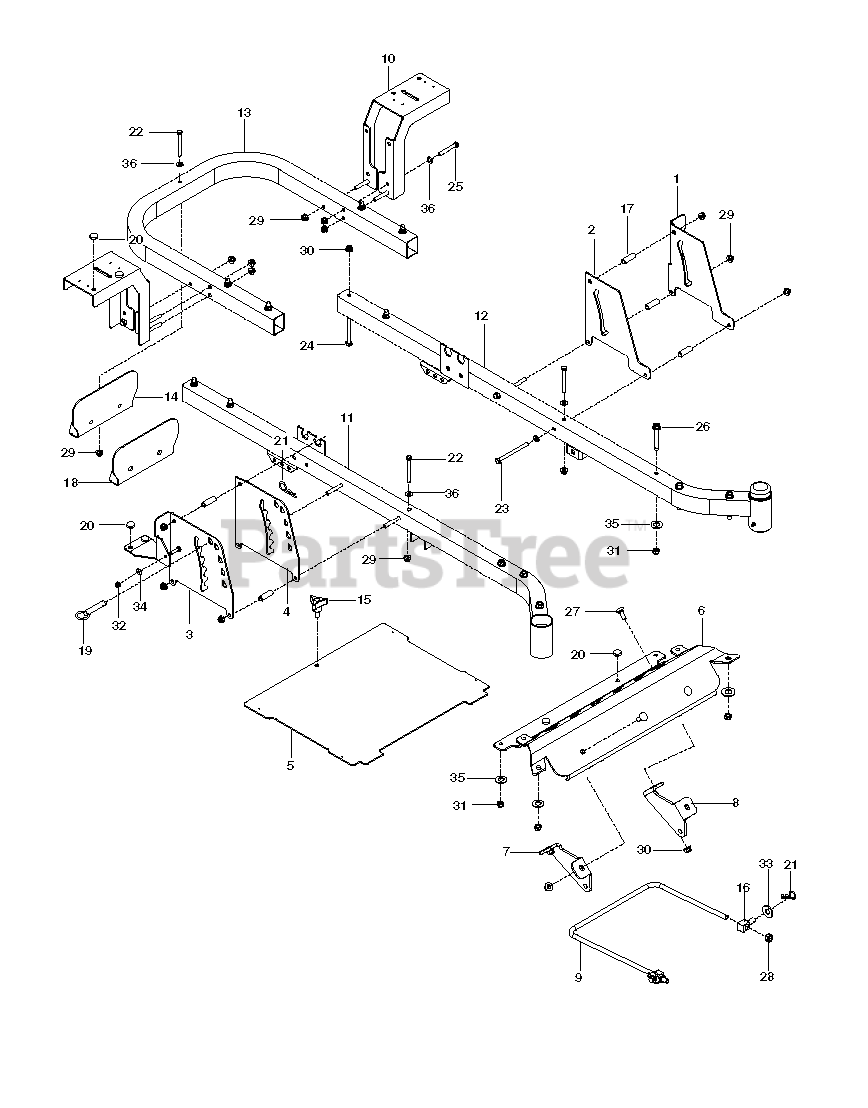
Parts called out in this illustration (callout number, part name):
1	PLATE, OUTER BRAKE, BLACK
2	PLATE, BRAKE LATCH, BLACK
4	PLATE, DECK HEIGHT, BLACK
5	PLATE, FOOT W/DECALS SPZ
6	FOOT REST, MED BLUE
7	MOUNT, STRUT, RT, BLK
8	MOUNT, STRUT, LT, BLK
9	LINK, FRONT SUSP.
10	SUPPORT, FENDER, BLACK
11	FRAME, RT, BLUE
12	FRAME, LT, BLUE
13	FRAME TUBE, REAR, BLUE
14	PLATE, HITCH BLU
15	KNOB W/STUD
19	HITCH PIN
20	GROMMET, BUMPER
21	HAIRPIN #4
22	HCS 5/16C X 2-3/4
23	HCS 5/16C X 4
24	HCS 3/8C X 3
25	CAPSCREW
26	ENGINE BOLT, SPECIAL
27	RHSNB 3/8C X 1
28	7/16-14 HEX NUT W/NYL RING ZD
29	5/16-18 NYLOC FLANGE NUT
30	NUT 3/8-16 HEX FLG NYLOC ZD
31	NUT HEX 3/8-16 NYLON, THIN
32	NUT 1/4-20 NYLOC
33	WASH USS FLAT 1/2
34	WASHER 1/4 SAE
35	WASHER 3/8 FLAT
36	FLAT WASHER 5/16 SAE
